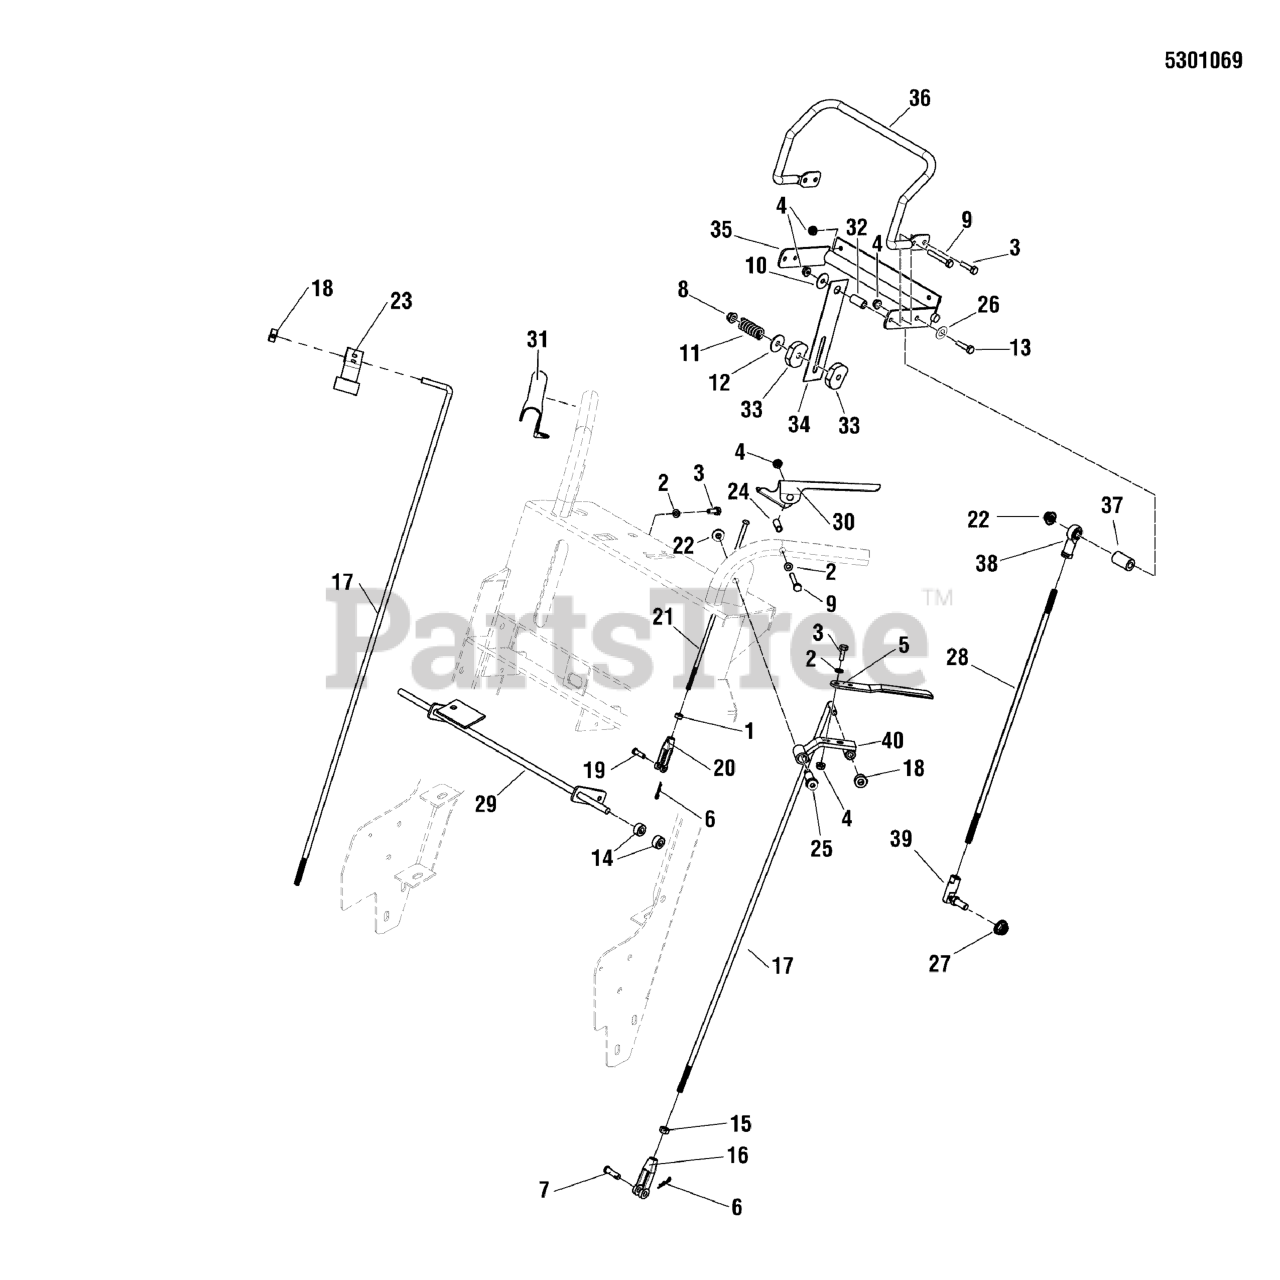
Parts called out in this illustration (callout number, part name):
1	HN, 1/4F GR5 YZ
2	WASHER, 1/4 SAE
3	BOLT, 1/4-20 X 3/4 GD5 YZ
4	NUT, 1/4-20 HEX NYLOCK FLANGE
5	LEVER, REVERSE HANDLE
6	PIN, HAIR, .0585 X 1-1/8, 1/4 EYE, YZ
7	PIN, CLEVIS, 5/16 X 1 YZ
8	NUT, 5/16-18 HEX NYLOCK FLANGE
9	BOLT, 1/4-20 X 1-3/4" GD5 YZ
10	WASHER, 1/4" FENDER
11	SPRING, BRAKE
12	WASHER, 5/16" FENDER
13	BOLT, 3/8-16 X 2-1/2" GD5 CZ
14	COLLAR, 3/8" SET
15	NUT, 5/16-24 HEX
16	CLEVIS, 5/16-24, STEEL, CLEAR ZINC
17	ROD, REVERSING, SNP PRO WB
18	COLLAR, 5/16" SET
19	PIN, CLEVIS, 1/4 X 7/8, PLATED
21	ROD, OPC LINK, SNP PRO WB
22	NUT, 3/8-16 HEX NYLOCK FLANGE
23	WELD, REVERSE HANDLE - RH
24	SPACER, .26 X .38 X 1.250, YZ
25	BOLT, 3/8-16 x 1-1/2", 1/2" SHOULDER
26	WASHER, 3/8 SAE
27	NUT, 3/8-24 HEX NYLON LOCK
28	ROD, CRUISE CONTROL, SNP PRO WB
29	WELD, OPC SHAFT- RED
32	SPACER, .26 X .50 X 1.00 YZ
33	DDS BRAKE PUCK
34	PLATE, FRICTION CONTROL
35	WELD, SPEED CONTROL,DDS - RED
36	BAR, SPEED CONTROL, DIPPED
37	SPACER, .38 X .75 X 1.25, YZ
38	ROD END, 3/8-24 LH FEMALE
39	BALL JOINT, 3/8-24 FEM, STUD.
40	WELD, REVERSE HANDLE - LH
